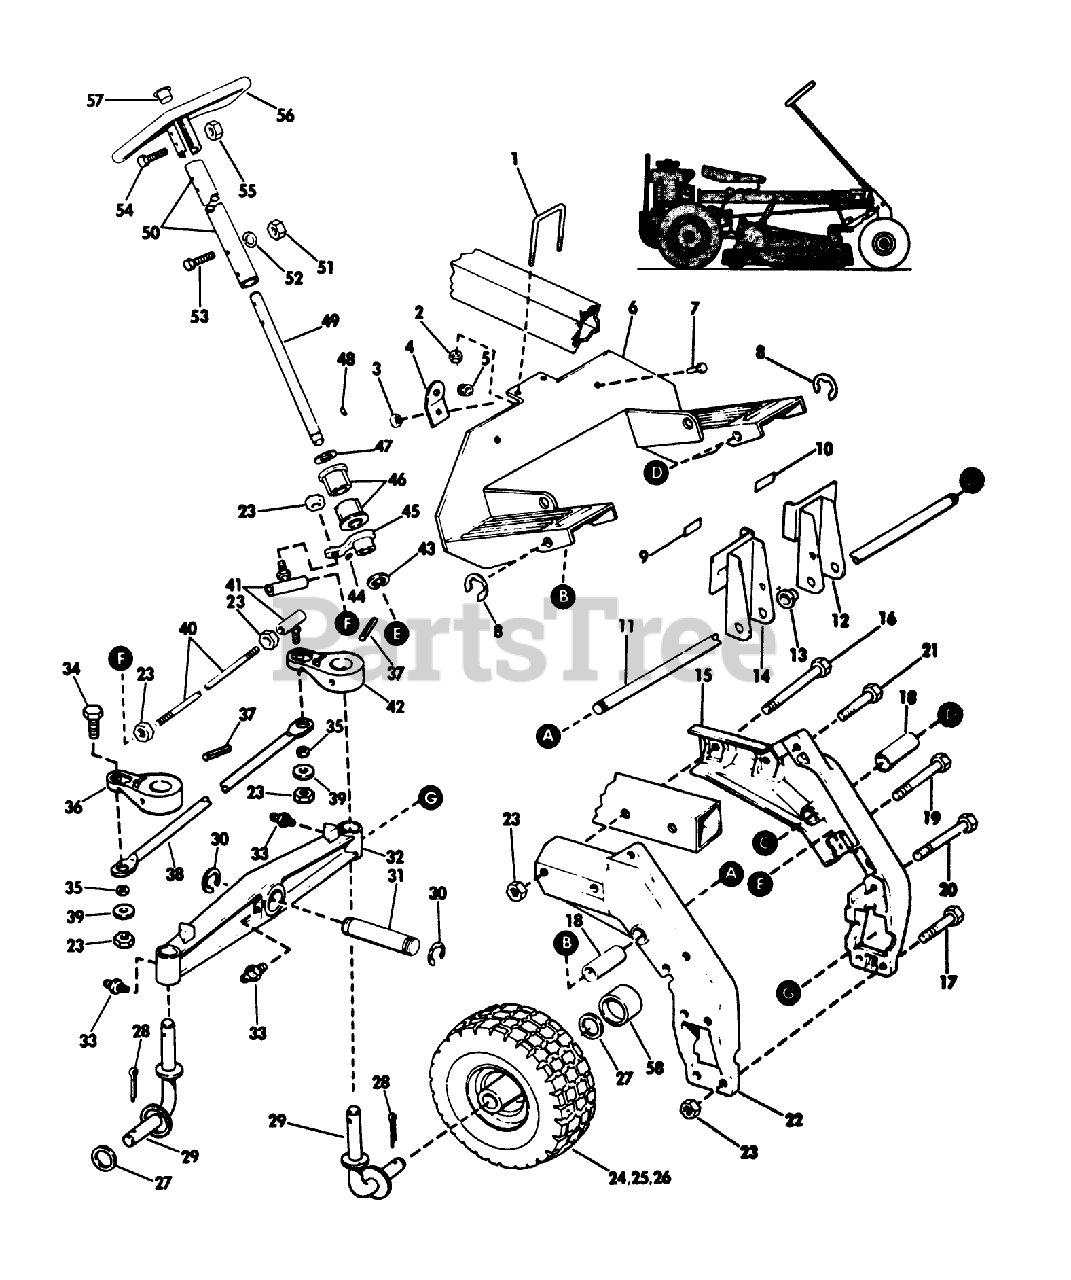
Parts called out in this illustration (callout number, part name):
5	Bushing
33	Grease Fitting
34	Screw-King Pin
55	Nut-Steering Shaft
